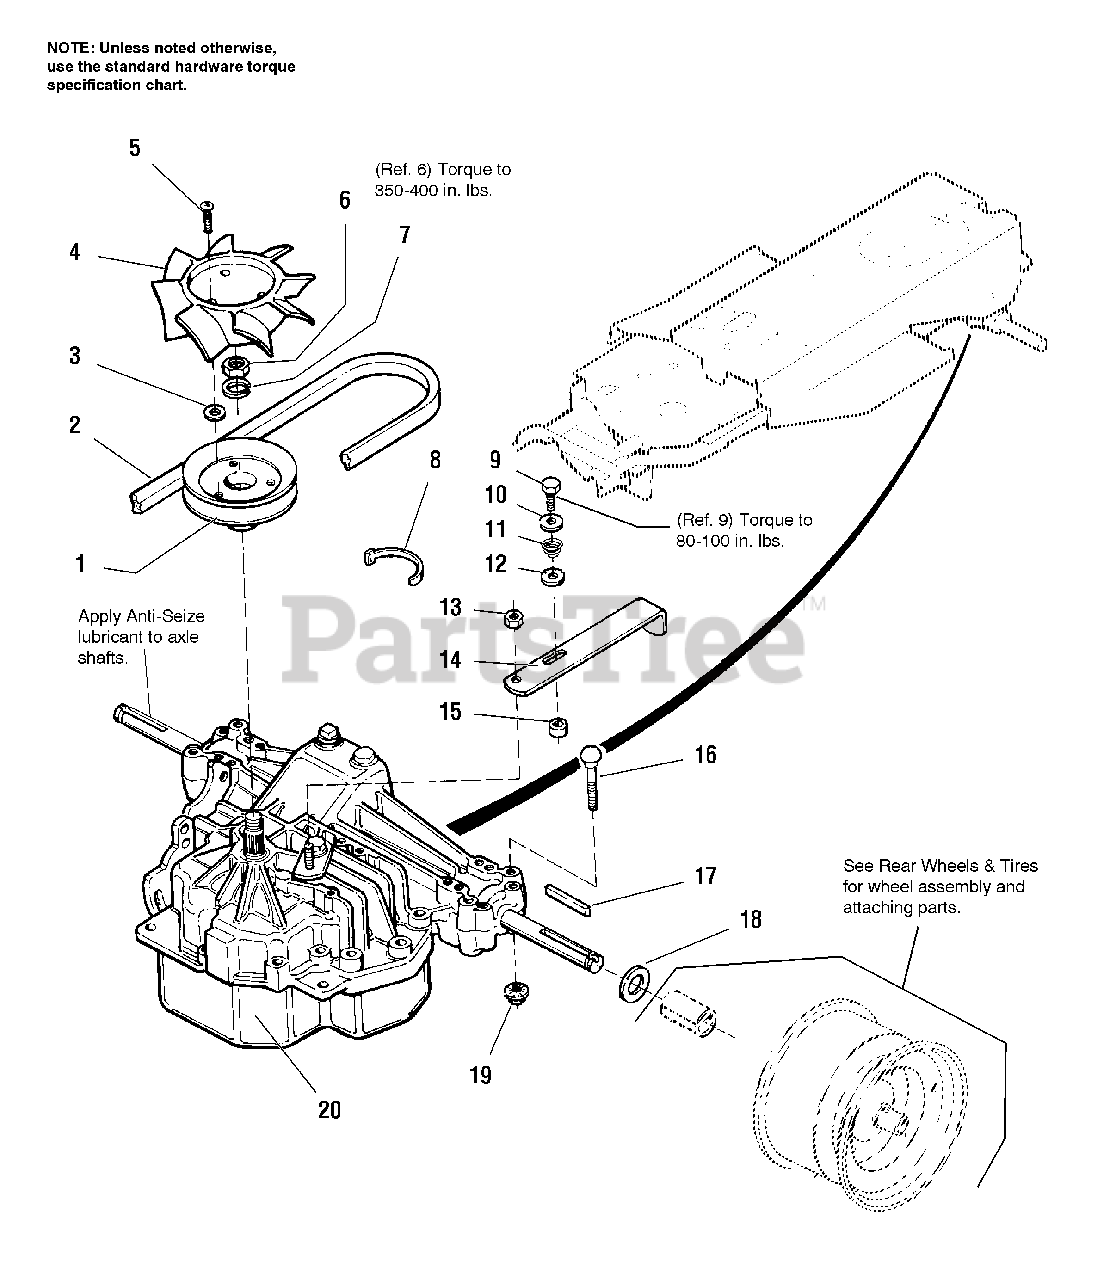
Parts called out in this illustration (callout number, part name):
1	PULLEY ASSY.
2	BELT, Drive
3	WASHER, Plain, 1/4
5	SCREW, Taptite, 1/4-20 x 1-1/8
6	JAM NUT, Hex, 1/2-20
7	LOCKWASHER, 1/2
9	SCREW, Taptite, #10-24 x 1-1/4
10	WASHER, 1/4 x 1-1/4 x 1/16
11	SPRING, Conical
12	WASHER
13	NUT, Hex, Full, Lock, 1/4-20
14	LEVER
16	CARRIAGE BOLT, 5/16-18 x 2-3/4
17	KEY
18	WASHER, 3/4
19	NUT, Hex Flange, small, 2-way lock, 5/16-18
20	TRANSAXLE, Hydro Gear 312-0800CT
